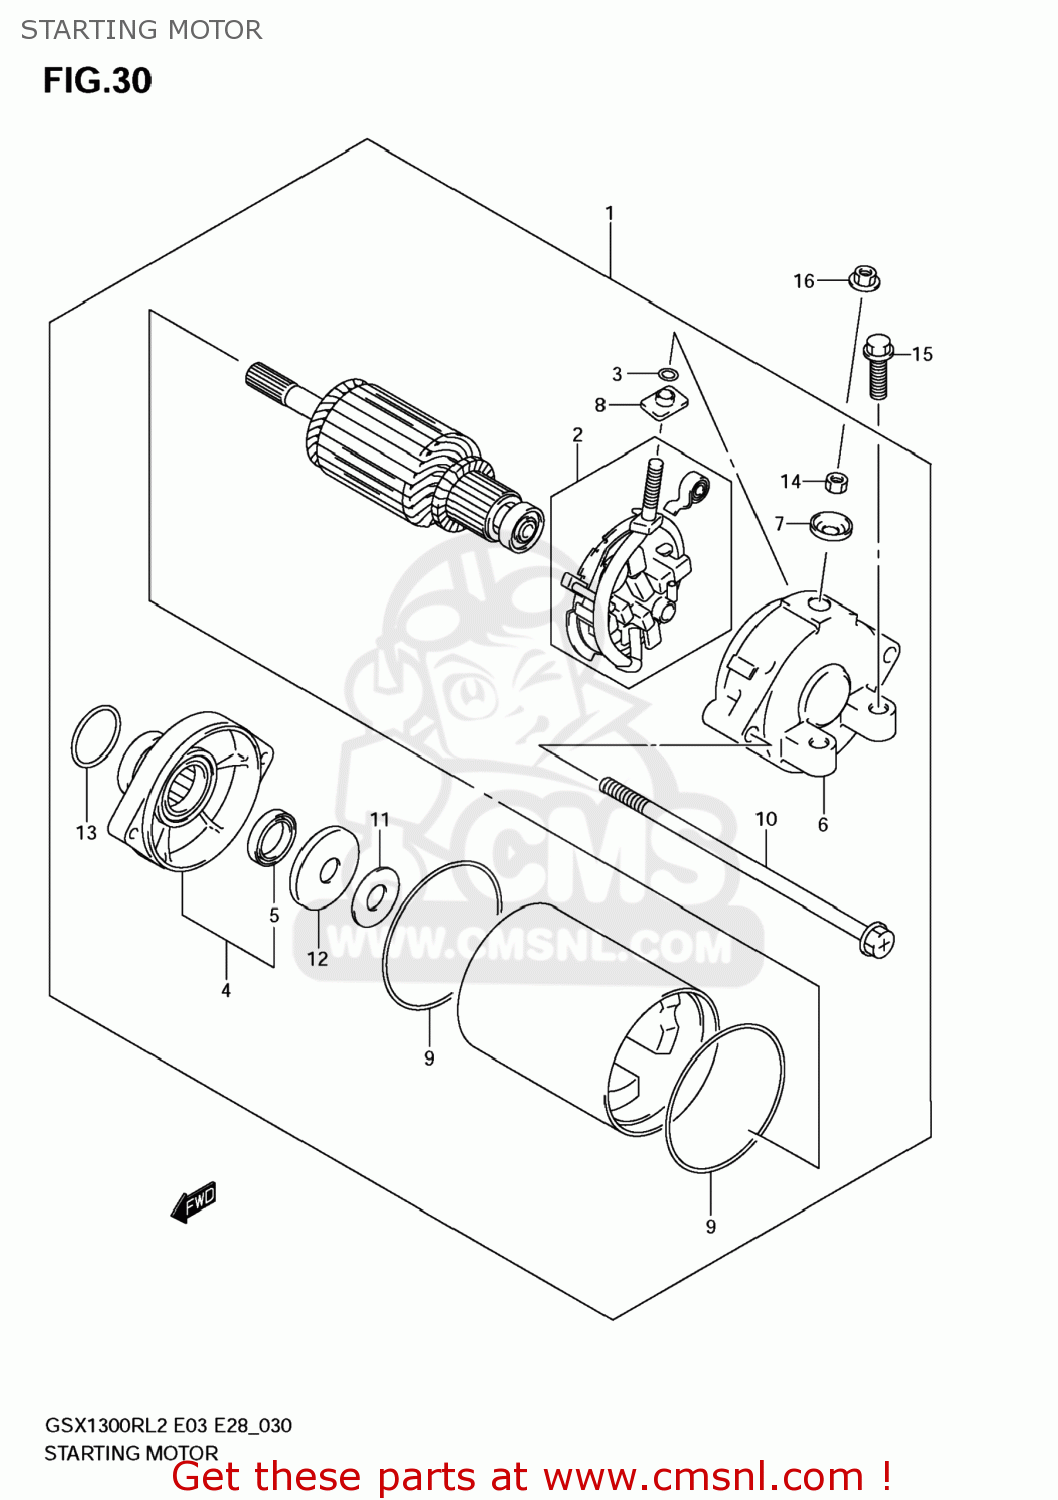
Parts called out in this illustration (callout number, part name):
1	MOTOR ASSY,STARTING
2	HOLDER SET,BRUSH
3	O RING
4	HOUSING ASSY,STARTER
5	SEAL,OIL
6	FRAME,STARTER END
7	BUSHING
8	BUSHING
9	O RING
10	BOLT
11	SHIM
12	WASHER
13	O RING(D:3,ID:24.5)
14	NUT
15	BOLT(6X25)
16	NUT
